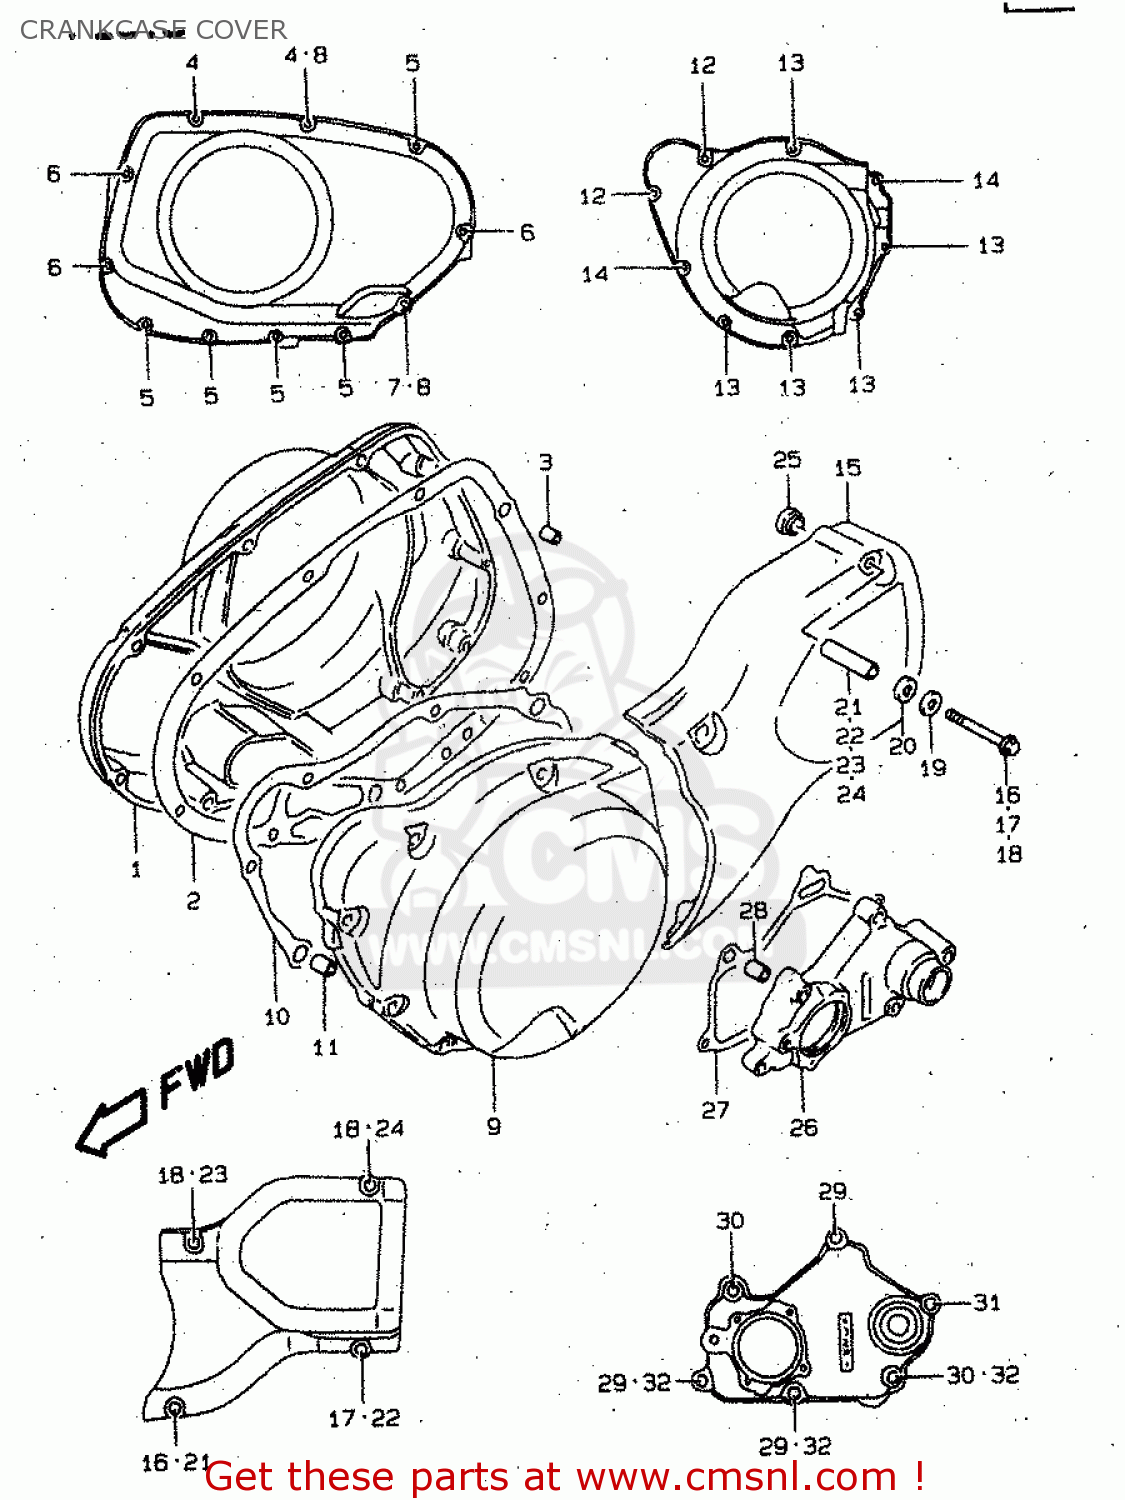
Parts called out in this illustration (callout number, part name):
1	COVER,CLUTCH
2	GASKET,CLUTCH COVER (NAS)
3	PIN
4	BOLT
5	BOLT
6	BOLT
7	BOLT
8	GASKET(5.8X11X1.2) (NAS)
9	COVER,GENERATOR
10	GASKET,GENERATOR COVER (NAS)
11	PIN(8.4X11X20)
12	BOLT
13	BOLT
14	BOLT
15	COVER,SECONDARY GEAR CASE
16	BOLT
17	BOLT
18	BOLT
19	WASHER
20	WASHER(8.7X16X5)
21	SPACER(6.5X9X21)
22	SPACER(6.5X9X26)
23	SPACER(6.5X9X49)
24	SPACER (L=45.9)
25	WASHER(8.7X16X5)
26	COVER,GEAR SHIFT
27	GASKET,GEAR SHIFT COVER (NAS)
28	PIN
29	BOLT
30	BOLT
31	BOLT
32	GASKET(5.8X11X1.2) (NAS)
